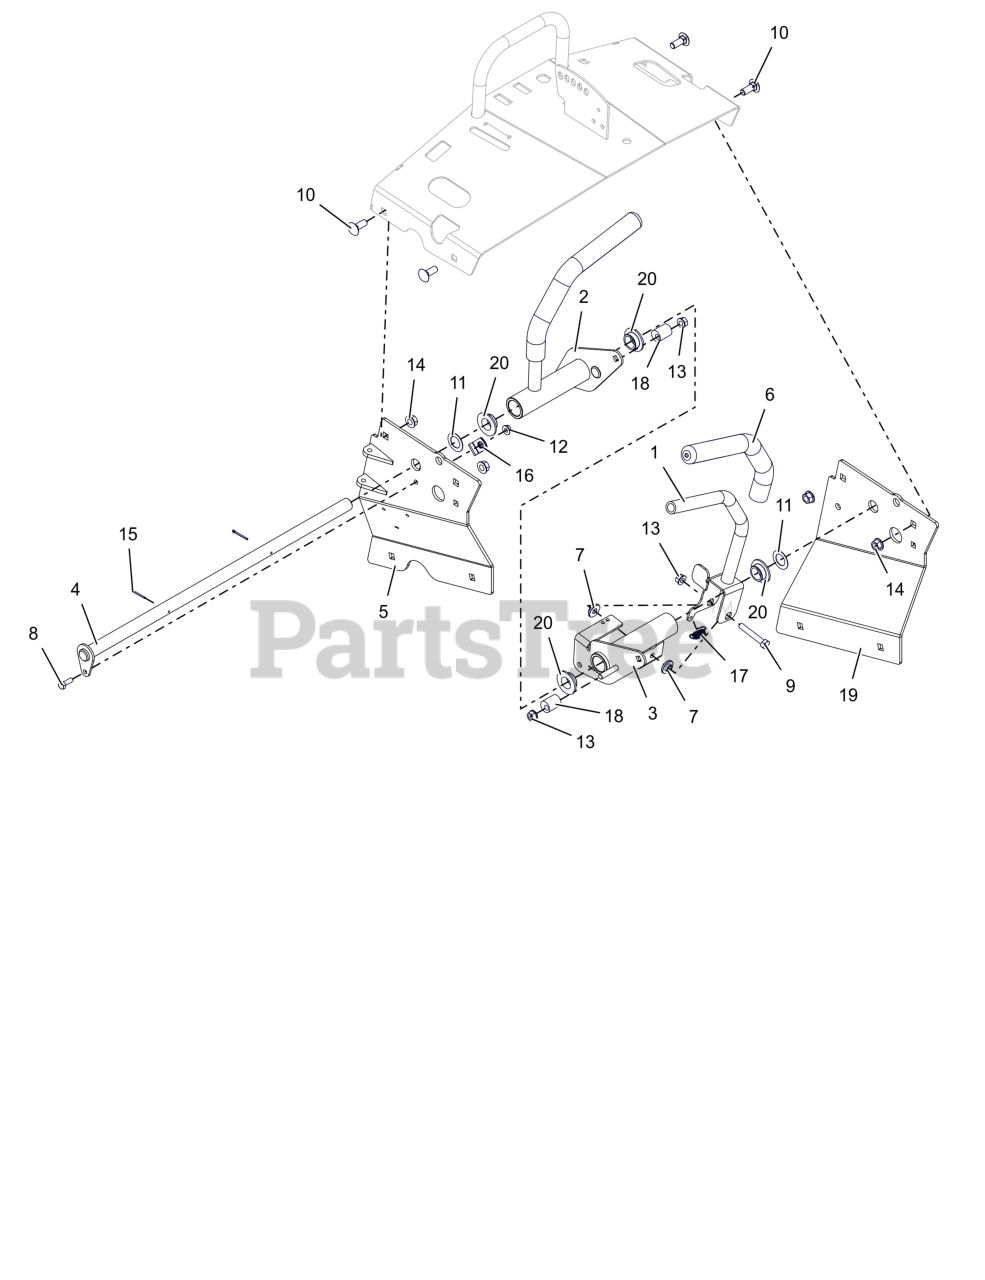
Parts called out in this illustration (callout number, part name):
1	WLDMT-LH STEERING CONTROL(BLK)
2	WLDMT-RH STEERING CONTROL(BLK)
3	WMT-LH STEER CNTRL PIVOT (BLK)
4	WMT- CONTROL PIVOT SHAFT
5	WLDMT-32"TOWER RH SUPPORT(RED)
6	GRIP, HANDLEBAR
7	BSHG, FLG .325X.499X.26X.88
8	BLT, HEX .25-20X.75 G5 ZCC
9	BLT, HEX .31-18X2.00 G5 ZCC
10	BLT, RHSN .38-16X1.00 G5 ZCC
11	WSHR-FL-STL 0.76X1.225X0.032 ZCC
12	NUT-LK-CTR-FLG .25-20 ZC120
13	NUT,LK-CTR-FLG .31-18 GF ZCC
14	NUT-LK-CTR-FLG .375-16 GF ZCC
15	PIN-COTR .09X1.0 PL
16	CLAMP, CUSHIONED STEEL .75
17	SPRING, EXT. .043X.438X1.64
18	ECCENTRIC
19	SUPPORT- 32" TOWER LH (RED)
20	BSHG, FLANGED .762 X 1.48 X .44 IGLIDER
